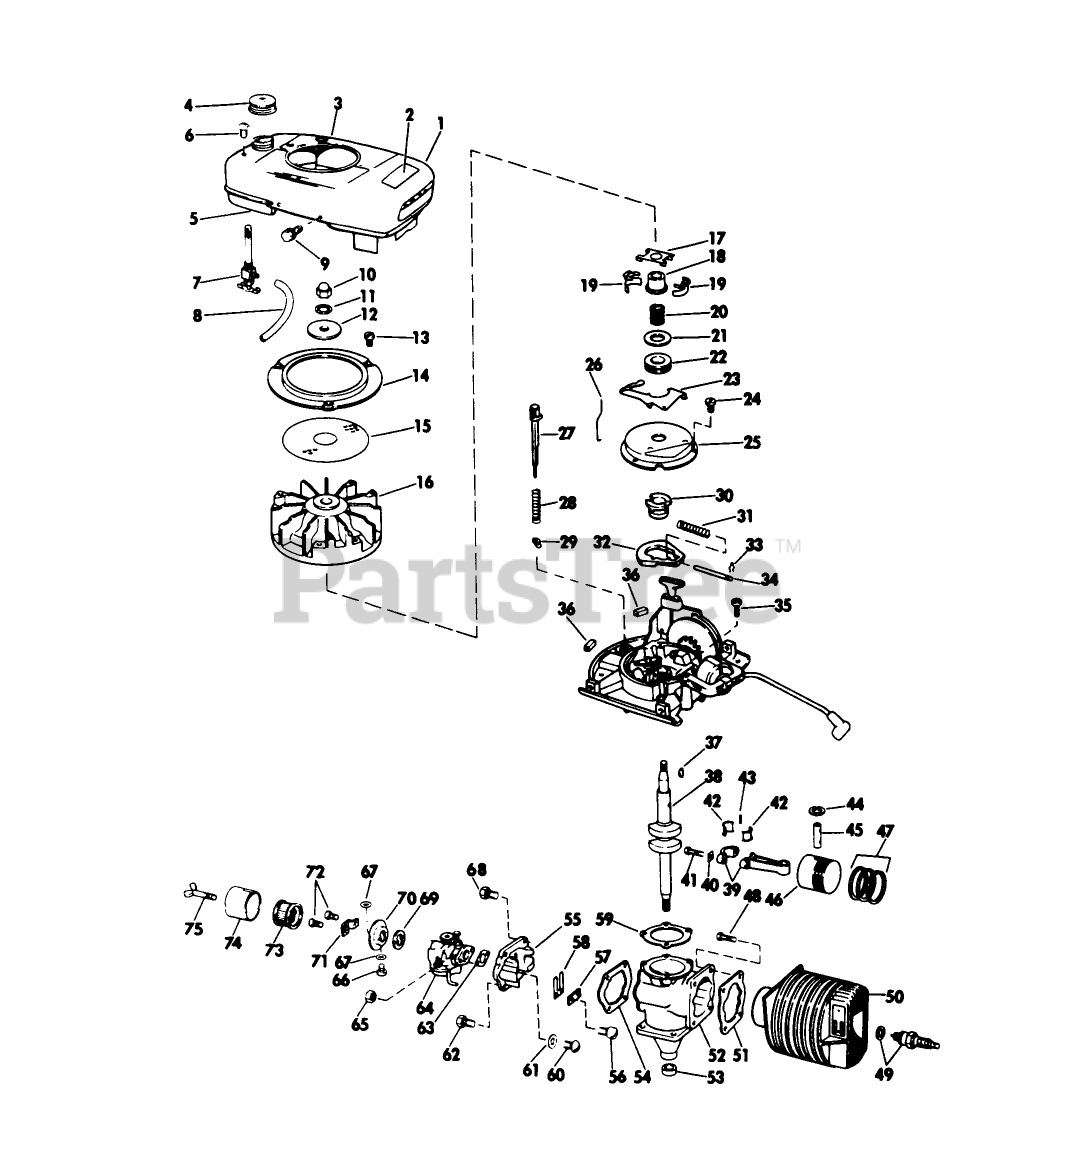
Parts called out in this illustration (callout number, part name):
7	VALVE&SCREEN SM
9	SCREW S
14	Ring-Flywhl. Scrn.
18	COLLAR S
22	THRUST COLLAR S
23	LEVER-GOVERNOR S
24	SCREW S
25	DUST COVER S
28	SPRING S
30	SPARK ADV. S
31	SPARK ADV. SPRING S
32	FLYWEIGHT S
33	SPARK ADJ. SPRING
34	PIN,SPARK ADV. S
42	LINER ASM
44	RING-RETAINING
49	Spark Plug
51	GASKET S
57	PLATE-BACKUP, REED
59	GASKET S
62	SCREW S
63	GASKET S
65	STOP NUT
68	SCREW S
69	GASKET S
